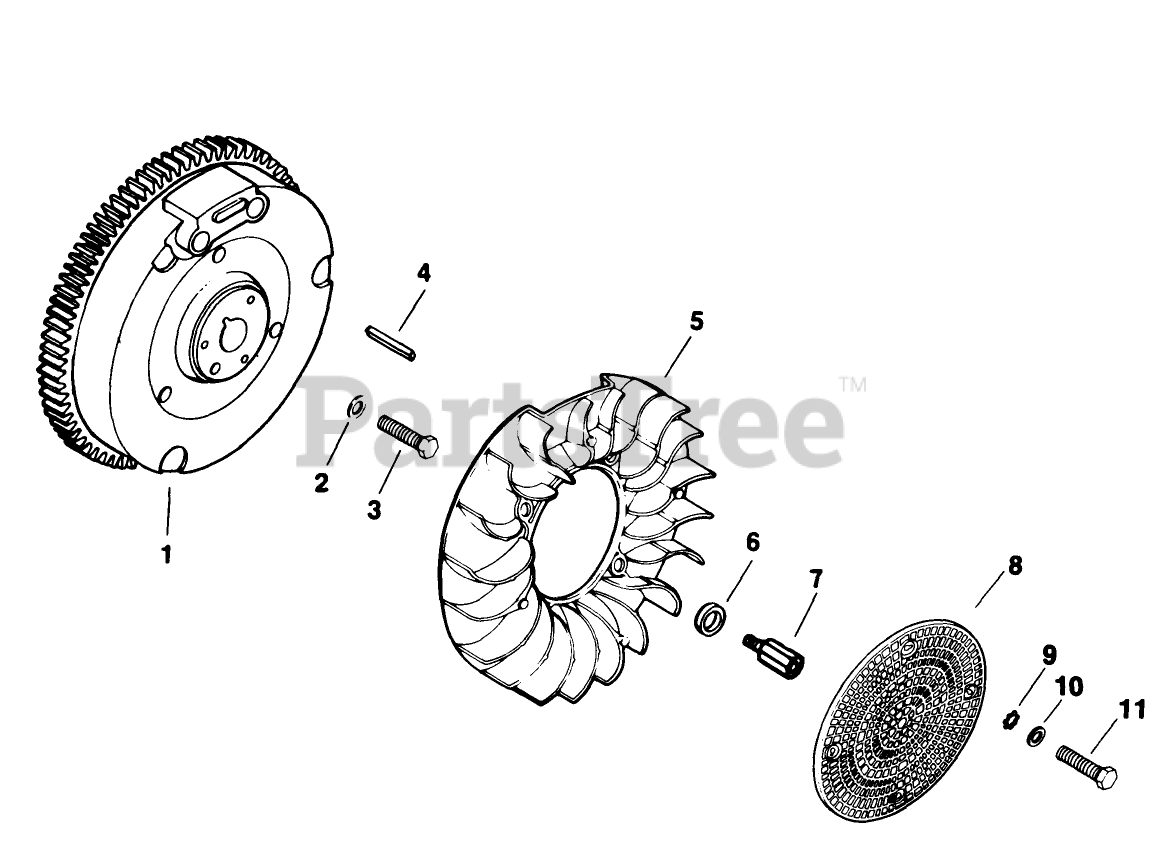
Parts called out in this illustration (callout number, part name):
1	Flywheel
2	Washer-Flat
3	Screw-H.C.
4	Key
8	Screen-Grass
9	Washer-Lock
10	Washer
11	Screw-T.H.
